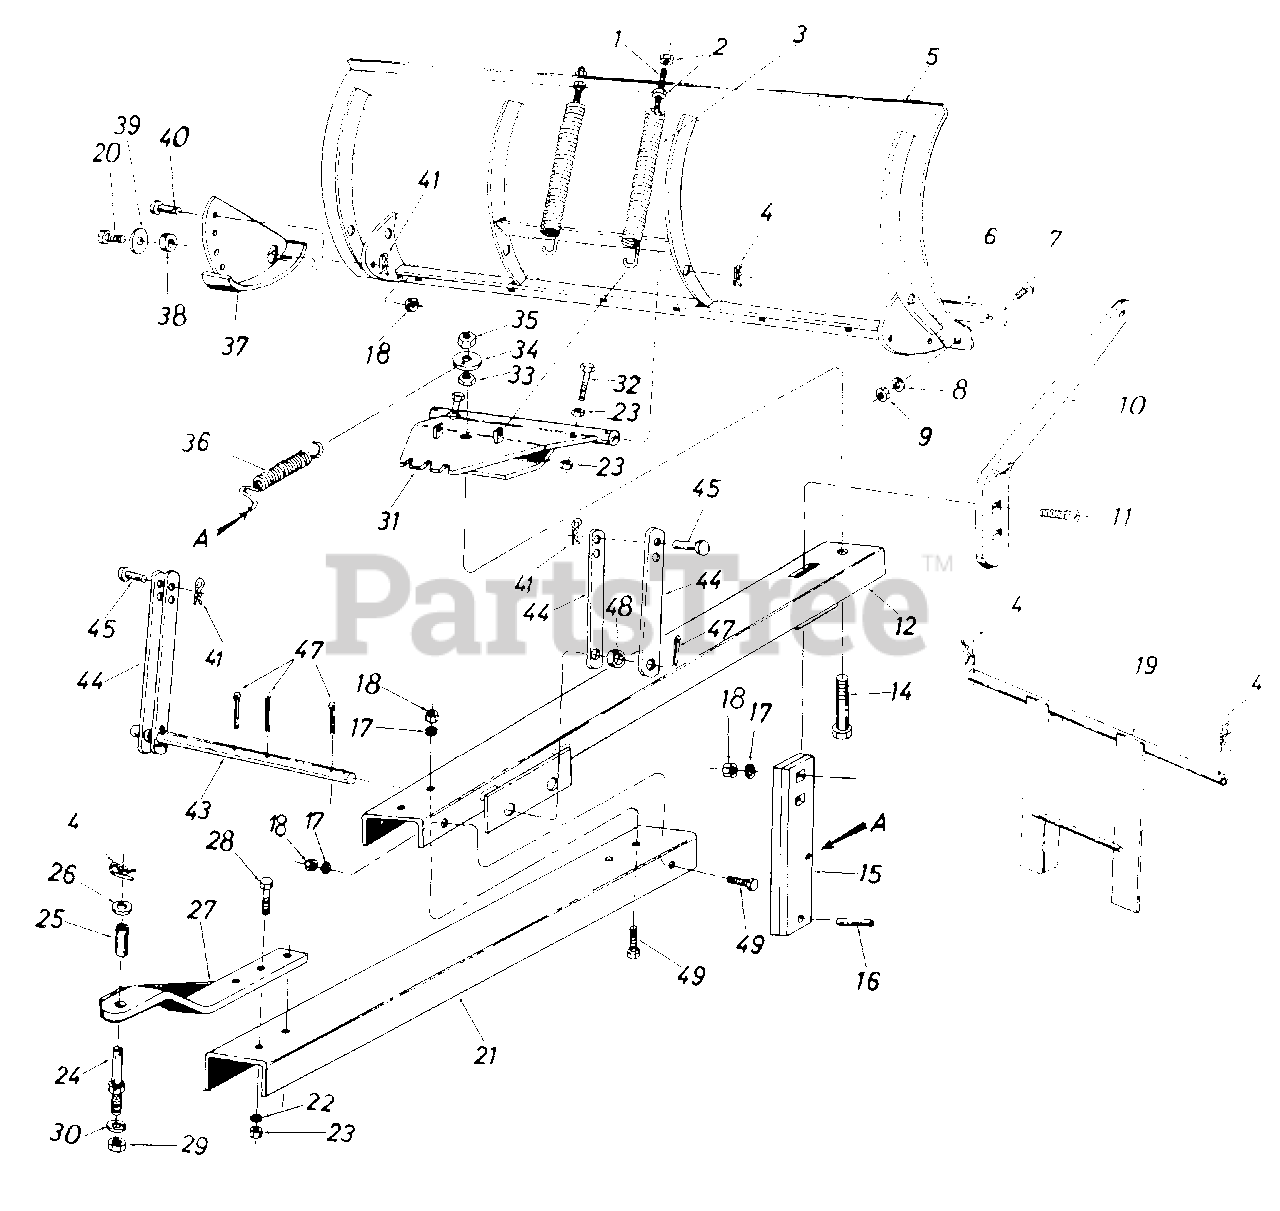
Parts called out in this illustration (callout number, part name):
1	Hex Bolt 3/8-16 x 4.5" Lg.
2	Hex Nut 3/8-16 Thd.
3	Blade Adjustment Spring
4	Int. Cotter Pin 5/32"
5	54" Blade Ass'y.
6	Wear Plate
7	Carriage Bolt 5/16-18 x .75" Lg.
8	L-Wash. 5/16" I.D.
9	Hex Nut 5/16-18 Thd.
10	Lock Extension Bar
11	Carriage Bolt 3/8-16 x 1.25" Lg.
12	Front Push Bar Ass'y.
14	Hex Bolt 3/4-10 x 3.5" Lg.
15	Angle - Lock Bar
16	Spring Pin Spiral .25" Dia. x 1"
17	L-Wash. 3/8" I.D.
18	Hex L-Nut 3/8-16 Thd.
19	Guide Bracket Ass'y.
20	Hex Bolt 3/8-16 x .75" Lg.
21	Rear Push Bar Channel
22	L-Wash. 1/2" I.D.
23	Hex Nut 1/2-13 Thd.
24	Link Clevis Pin
25	Spacer 21/32" I.D. x .75" Lg.
26	Fl-Wash. 21/32" I.D. x .09" O.D.
27	Hitch Hanging Bar Ass'y.
28	Hex Bolt 1/2-13 x 1.25" Lg.
29	Hex Jam L-Nut 5/8-18 Thd.
30	L-Wash. 5/8" I.D.
31	Pivot Plate Ass'y.
32	Hex Bolt 1/2-13 x 2.0" Lg.
33	Hex Jam Nut 3/4-10 Thd.
34	Fl-Wash. 3/8" (Special)
35	Hex Lock Nut 3/4-10 Thd.
36	Angle Lock Spring
37	Skid Assembly
38	Bushing, Pivot Skid
39	Fl-Wash. .385" I.D. x 1.0" O.D.
40	Clevis Pin 5/16" Dia. x 3/4" Lg.
41	Int. Cotter Pin 3/32"
43	Lift Shaft
44	Lift Link
45	Clevis Pin 1/2" Dia. x 1.0" Lg.
47	Cotter Pin 1/8" Dia. x 1.25" Lg.
48	Spacer, Lift Link
49	Hex Bolt 3/8-16 x 1.0" Lg.
